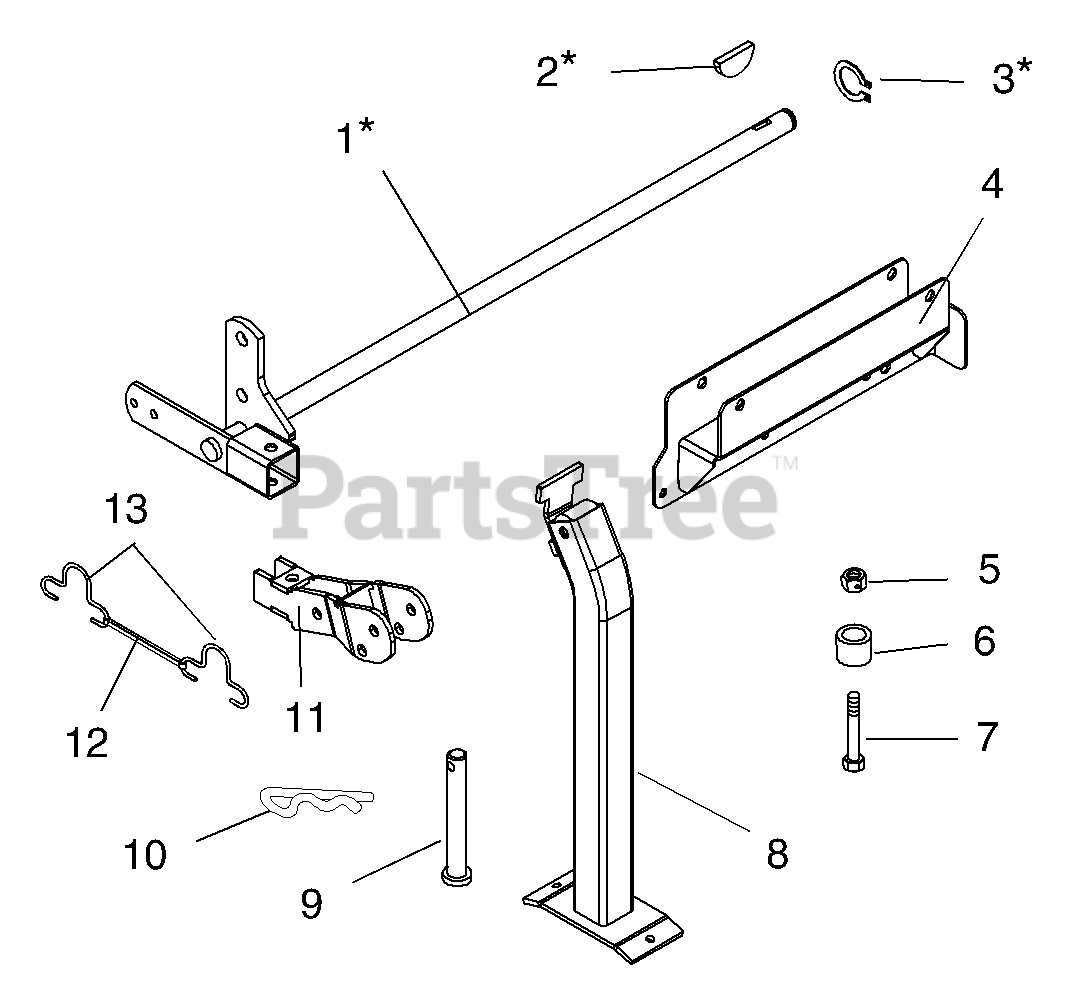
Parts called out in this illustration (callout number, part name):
1	Lift Arm
2	Woodruff Key
3	Retaining Ring
4	Lift Transport
5	3/8" Locknut
6	25/64" x 1" Spacer
7	3/8" x 1-3/4" Hex Bolt
8	Foot Weldment
9	Safety Pin
10	Hair Pin
11	Connector Weldment
12	Tie-Down Strap
